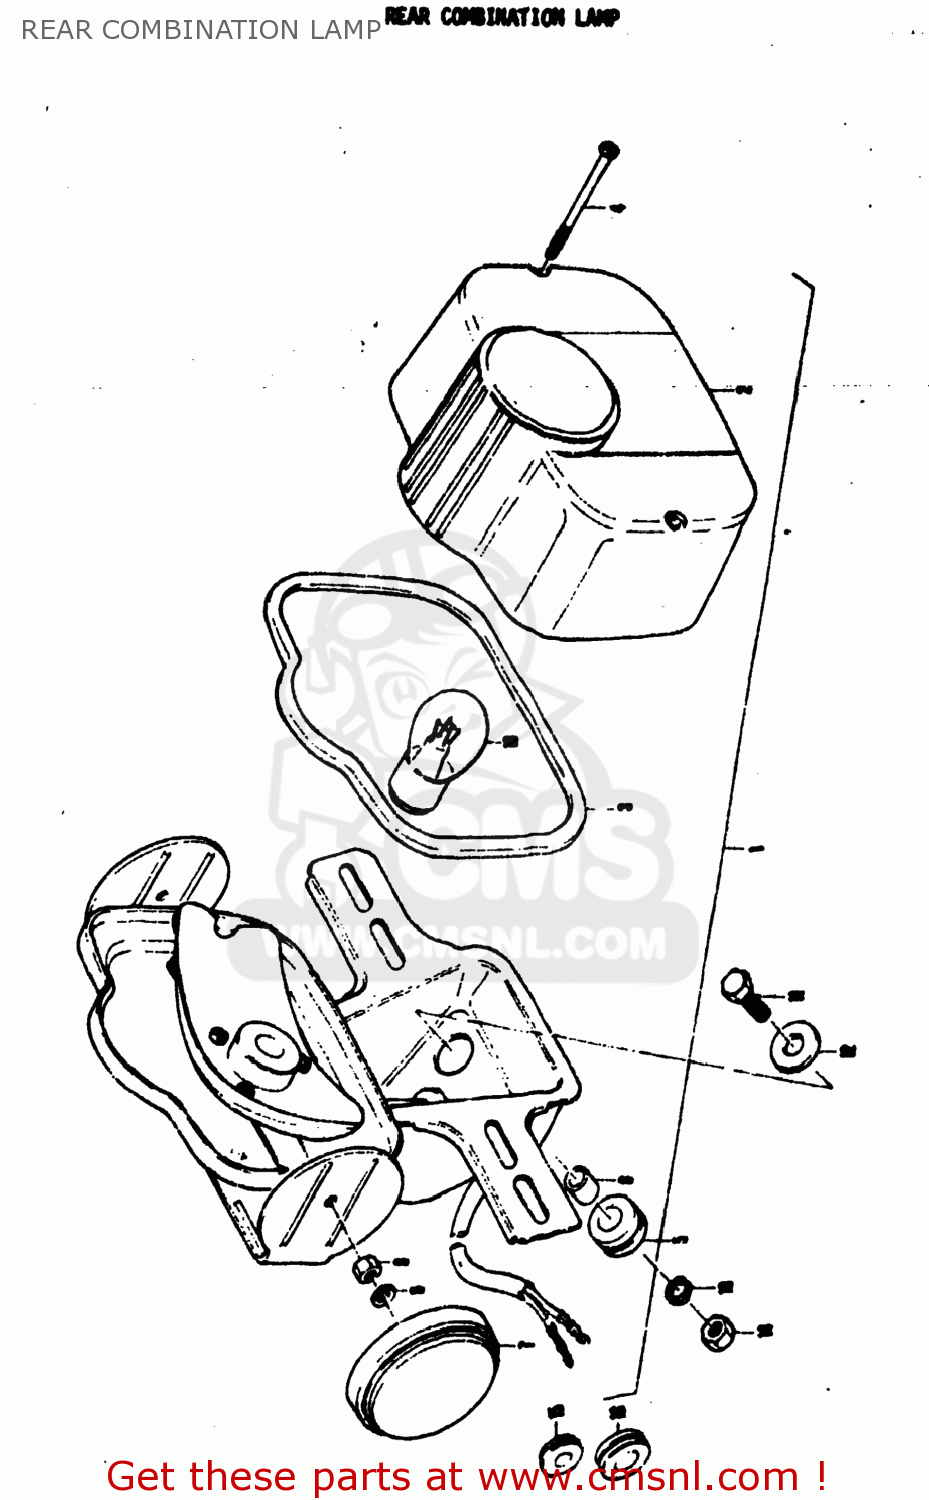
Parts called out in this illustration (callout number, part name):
1	CONVERSION KIT
2	LENS,REAR COMBINATION LAMP
3	GASKET,REAR COMBINATION LAMP LENS (NAS)
4	SCREW
5	WASHER,REAR COMBINATION LAMP
6	CUSHION
7	SPACER,REAR COMBINATION LAMP
8	REFLECTOR,REFLEX
9	SPACER,REFLECTOR,RIGHT
10	SPACER,REFLECTOR,LEFT
11	WASHER,REFLECTOR
12	LOCK WASHER
13	NUT
14	BULB(6V17/5.3W,STANLEY,A4813)
15	BOLT
16	WASHER
17	LOCK WASHER
18	NUT
19	GROMMET
20	GROMMET
